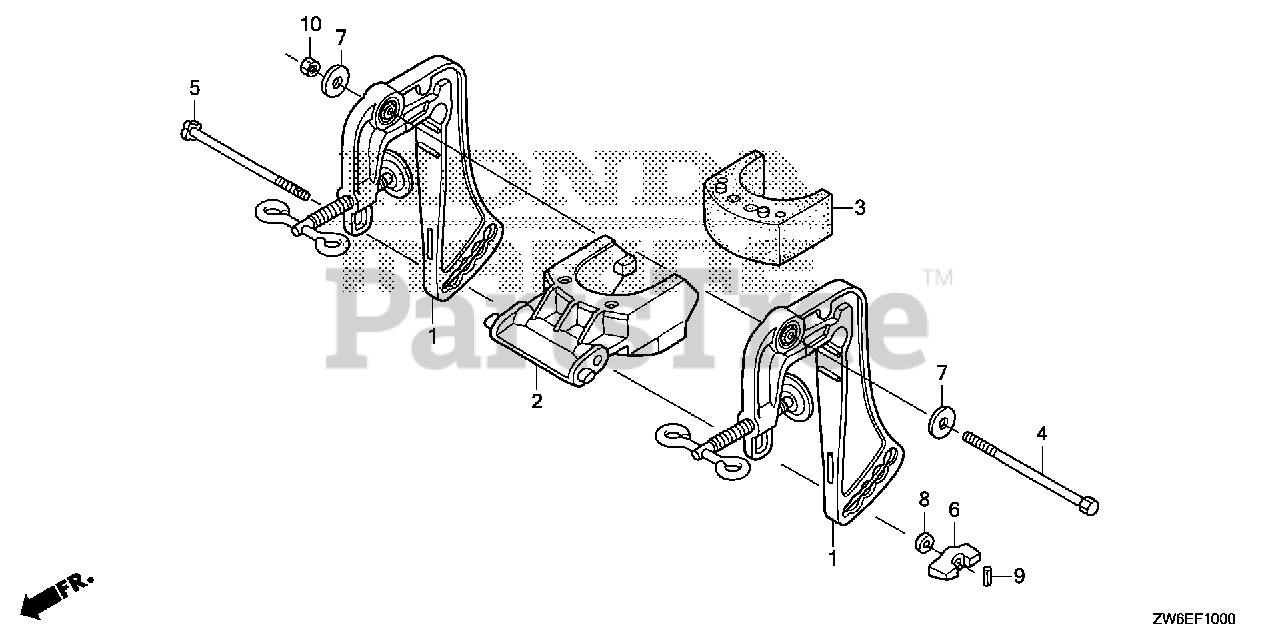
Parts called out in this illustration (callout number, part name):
1	BRACKET, STERN *NH246* (LOOSY GRAY)
2	RECEIVER, THRUST
3	RUBBER, THRUST
4	BOLT, HEX. (8X110)
5	BOLT, DIAMOND (6X110)
6	WINGNUT
7	WASHER, PLAIN (8MM)
8	WASHER, PLAIN (6MM)
9	PIN, SPRING (2.5X8)
10	NUT, HEX. (8MM)
